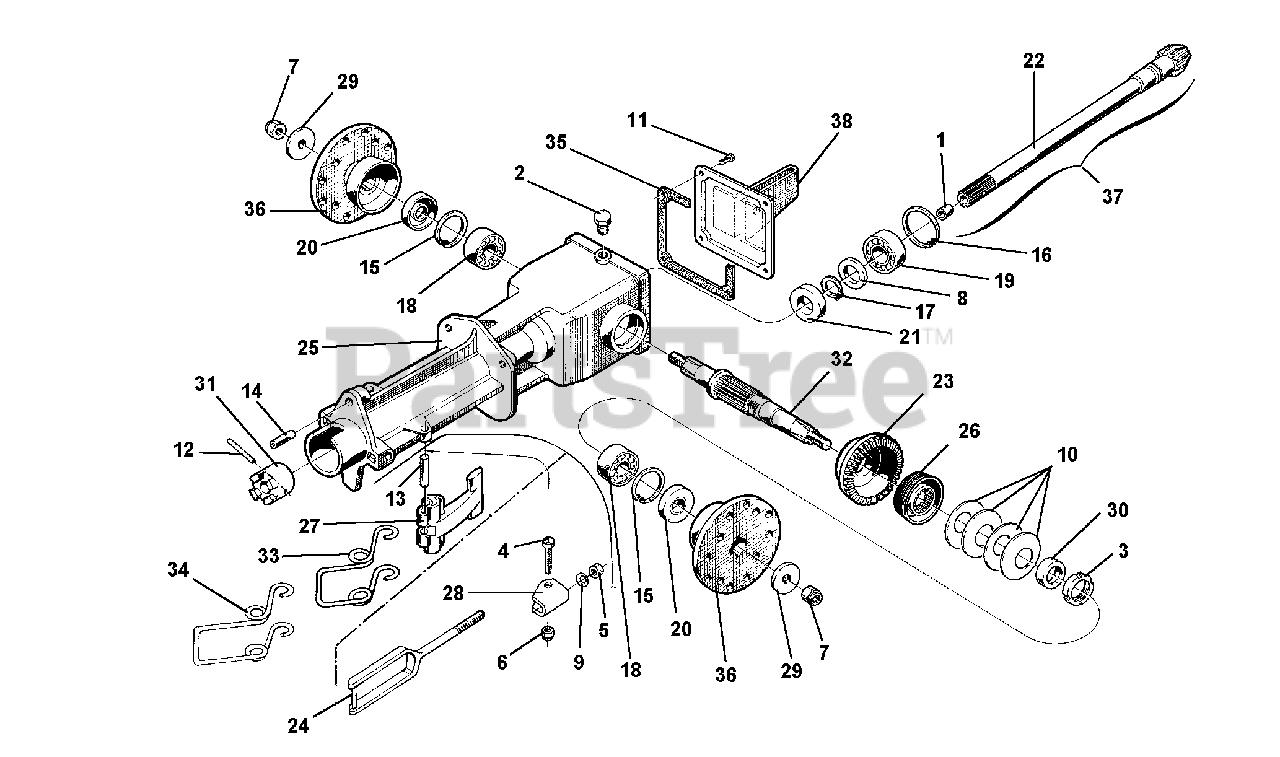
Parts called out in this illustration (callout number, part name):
2	PLUG 1/4 GAS
3	NUT, RING M25 X 1.5 SKF KM5
4	SCREW TE M8 X 30
6	NUT, SELF LOCKING M8
7	NUT, SELF LOCKING M12
8	WASHER FLAT 25
9	SUPER WASHER 8 DIN 6796
11	SCREW M6 X 12
12	PIN, LOCKING 6 X 40
13	SPIRAL PIN 8 X 40
14	LOCKING PIN 12 X 26
15	CIRCLIP, INTERN. D 47
16	CIRCLIP, INTERN. D 52
17	CIRCLIP, EXTERN. D 25 DIN 471
18	BEARING 20 X 47 X 14 6204
19	BEARING 25 X 52 X 15 6205
20	OIL SEAL 20 X 47 X 7
21	OIL SEAL 20 X 47 X 7
22	ROTARY HOE PINION
25	ROTARY HOE ASSEMBLY
26	CONE CLUTCH
28	IMPLEMENT HOOK COUPLING
29	WASHER WITH STEP
31	BAR COUPLING
32	ROTARY HOE SHAFT
34	LONG SPRING HOOK
36	KNIVE HOLDER FLANGE
37	ROTARY HOE PINION
